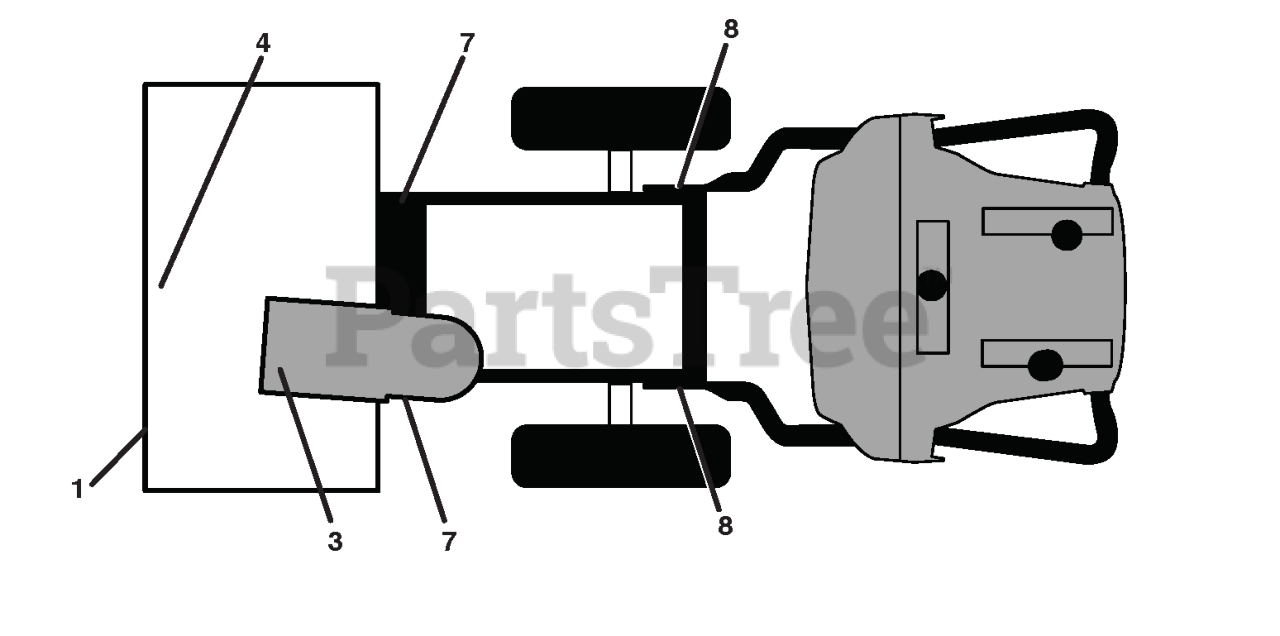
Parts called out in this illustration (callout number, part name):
1	DECAL.AUGER.POULAN PRO 24.208C
3	DECAL.CHUTE.SAFETY.EU/SC.17
4	DECAL.AUGER."
7	DECAL.BELT.GUARD.
8	DECAL.AUGER.SAFETY.
